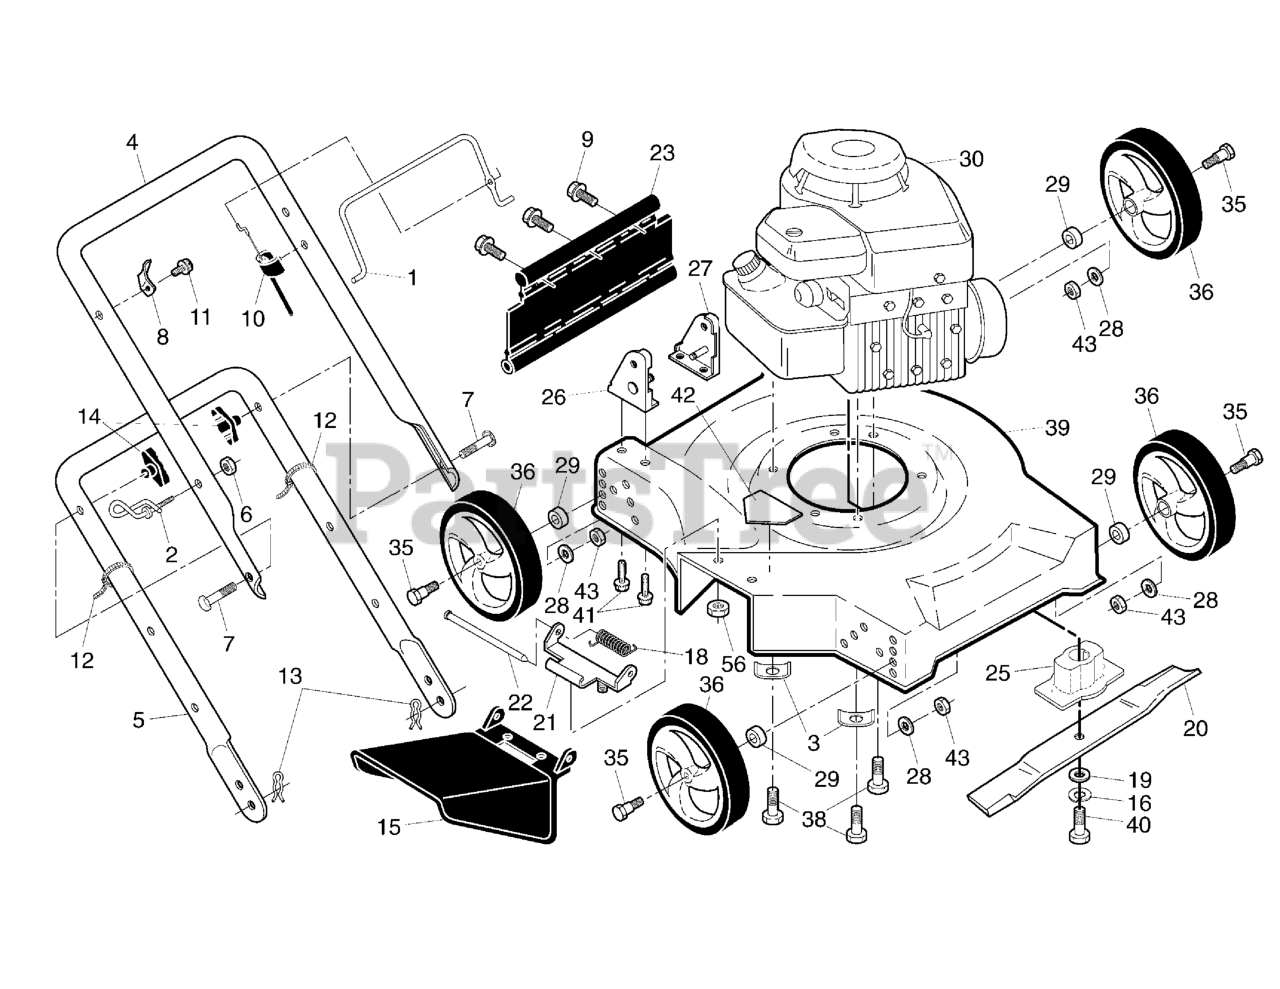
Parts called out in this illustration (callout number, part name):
1	Control Bar
2	Rope Guide
3	Washer, Special, Engine
4	Upper Handle
5	Lower Handle
6	Nut, Hex 1/4-20
7	Bolt, Carriage 1/4-20 x 1-1/2
8	Up-Stop Bracket
9	Screw, Hex Washer Head, Self Tapping, #10-24 x 1/2
10	Cable, Engine Zone Control
11	Screw, Threaded, Rolled, #10-24 x 1/2
12	Wire Tie
13	Hairpin, Cotter
14	Knob, Handle
15	Discharge Guard
16	Helical Lock Washer
18	Spring, Torsion
19	Washer, Hardened
20	Blade, 20"
21	Bracket, Hinge
22	Rod, Hinge
23	Rear Skirt
25	Blade Adapter
26	Handle Bracket Assembly, RH
27	Handle Bracket Assembly, LH
28	** Washer
29	Spacer
30	* Engine, Briggs & Stratton
35	Bolt, Shoulder 3/8-16 x 2-1/2
36	Wheel & Tire Assembly
38	Screw, Hex Head, Threaded, Rolled, 3/8-16 x 1
39	Housing Kit
40	Screw, Hex Head Machine, 3/8-24 x 1-3/8, Grade 8
42	Danger Decal
43	Nut, Hex, Nylock 3/8-16
56	Locknut, Hex 1/4-20
